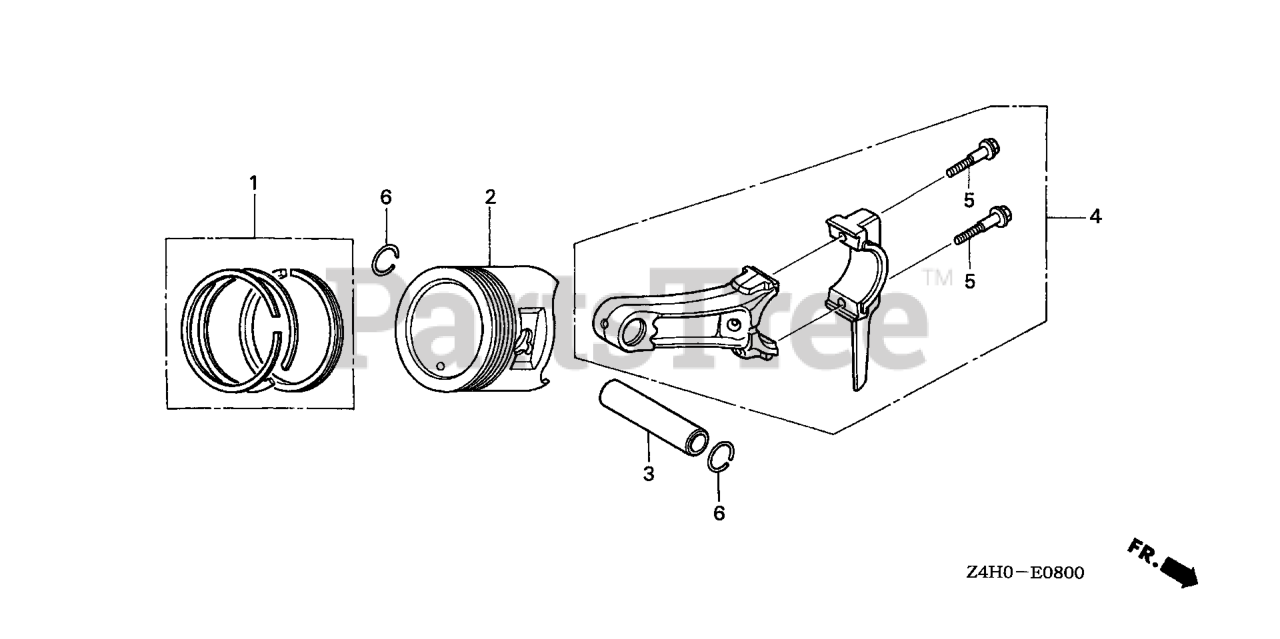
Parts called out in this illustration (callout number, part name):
1	RING SET, PISTON (STD) (TPR)
1	RING SET, PISTON (STD) (RIKEN)
2	PISTON (STD)
3	PIN, PISTON
4	CONN ROD ASSY.
5	BOLT, CONNECTING ROD
6	CLIP, PISTON PIN (13MM)
